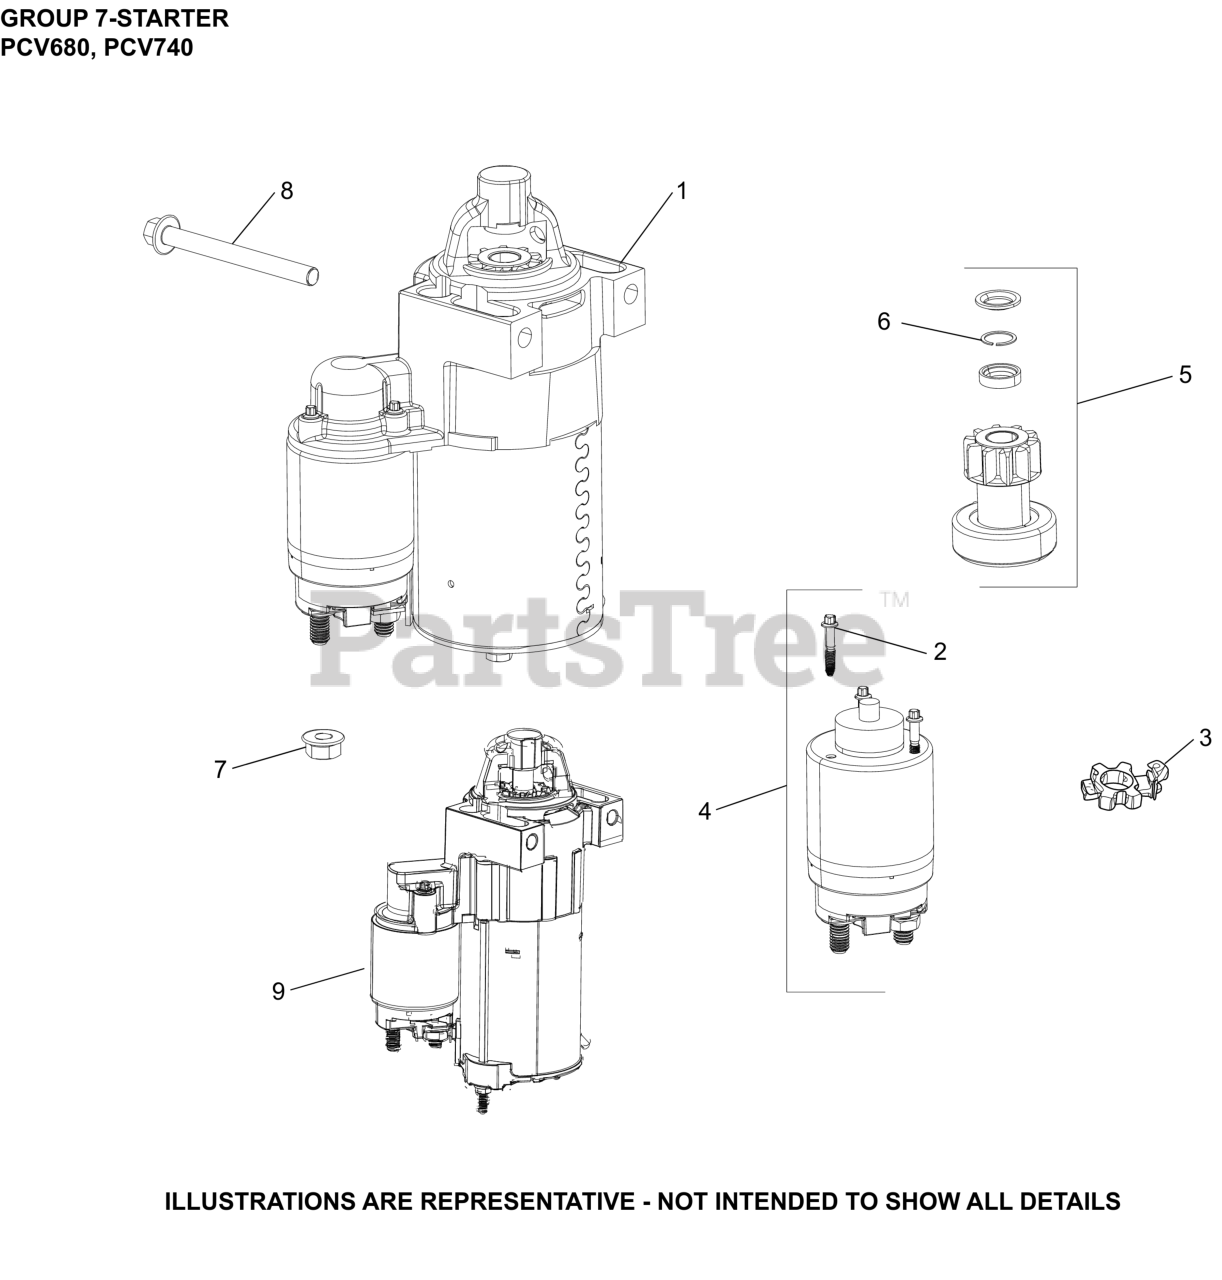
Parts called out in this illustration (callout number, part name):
7	NUT, FLG M8X1.25
8	SCREW, FLG M8X1.25X80
NI	STARTER, SOLENOID SHIFT
